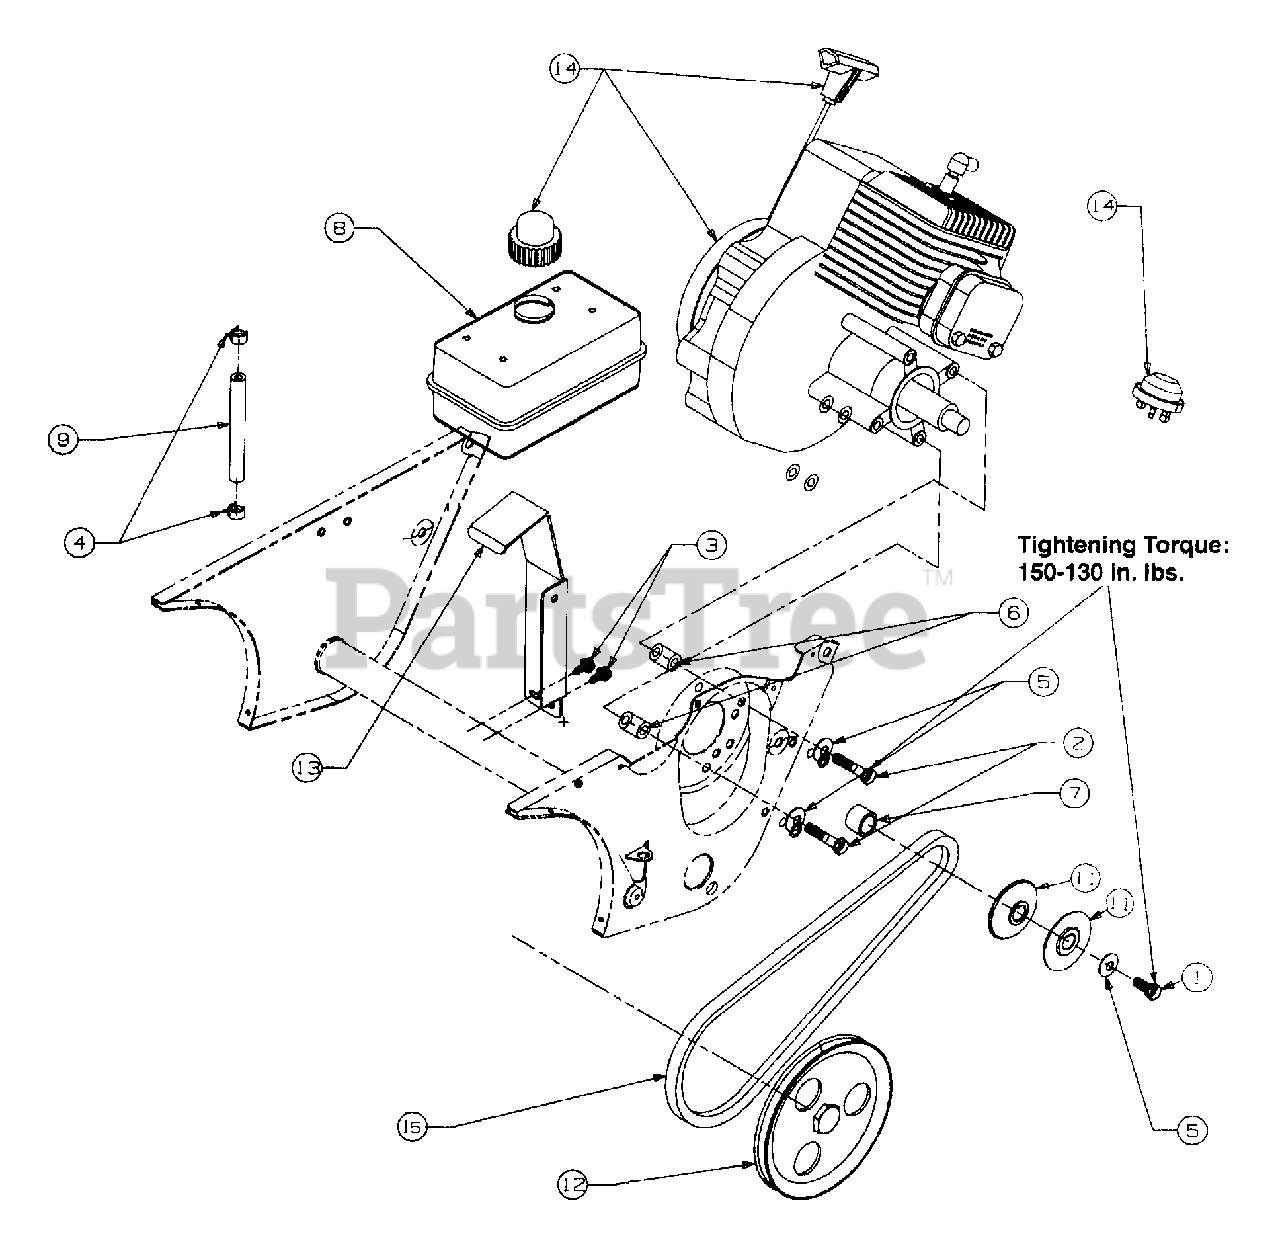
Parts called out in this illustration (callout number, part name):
1	Bracket - Support Gas Tank
2	Screw - Hex Cap
4	Screw - Hex
5	Screw - Washer
6	Screw - Hex Cap
7	Clamp - Hose
8	Washer - Lock
9	Washer - Bell
11	Bushing - Plastic
12	Hose - Fuel Line 16"
13	Tank - Fuel 2 Qt.
14	Cap - Fuel
15	V-Belt
